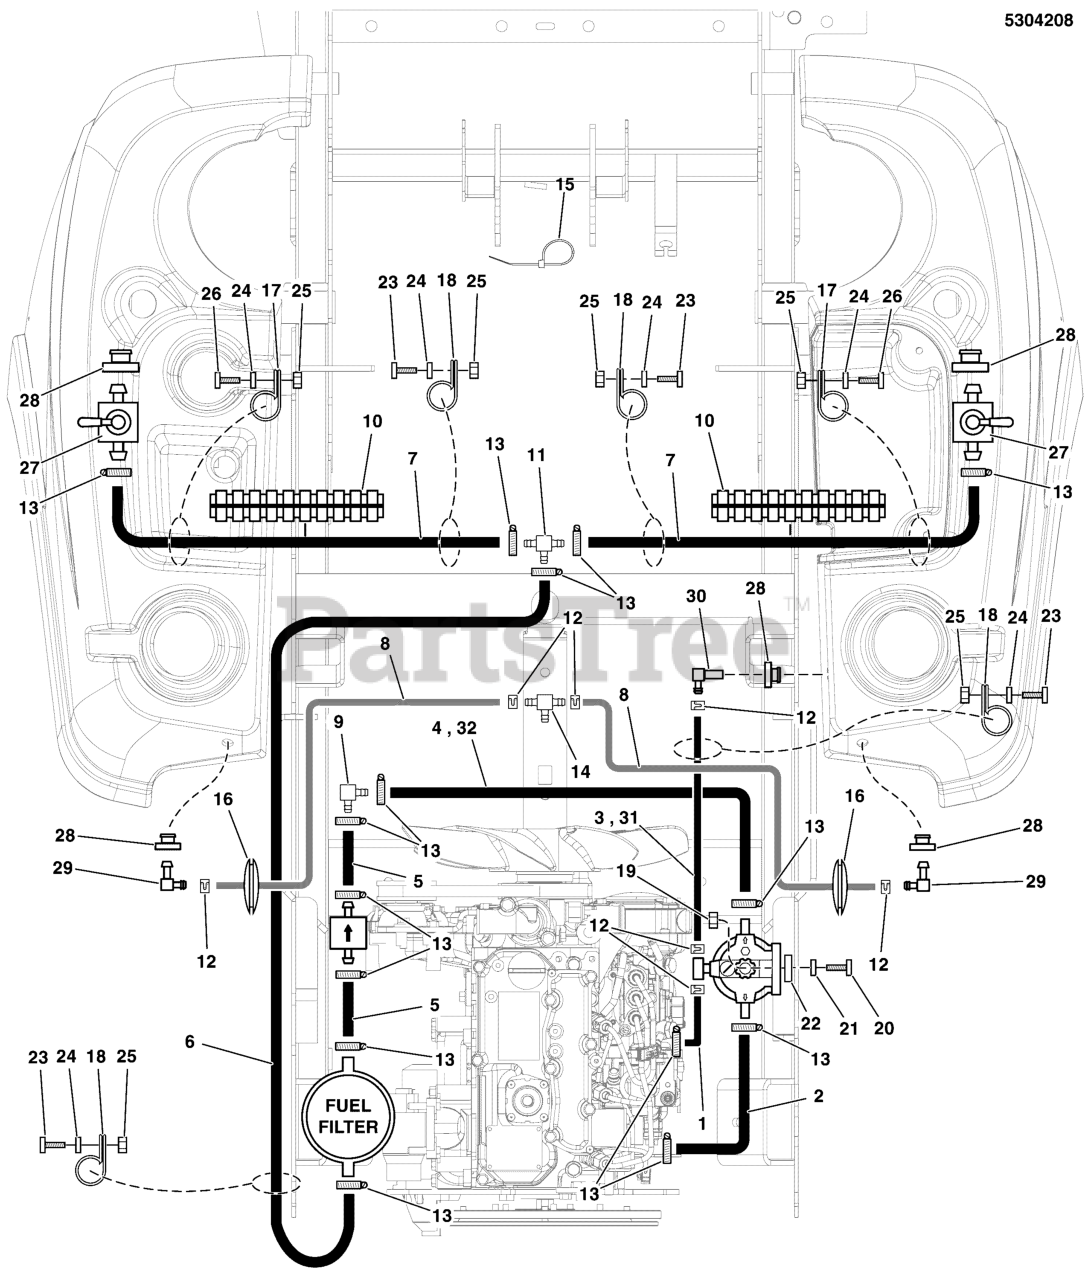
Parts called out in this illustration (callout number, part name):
1	HOSE, 1/4" FUEL, 22.50"
2	FUEL HOSE, 5/16 ID X 21.00
3	HOSE, 1/4" FUEL, 57.50"
4	FUEL LINE, 5/16 ID X 32.00 IN
5	FUEL LINE, 5/16 ID X 2.00 IN
6	FUEL HOSE, 5/16 ID X 40"
7	FUEL HOSE, 5/16 ID X 25.50
8	HOSE, 1/4" FUEL, 19.00"
9	FITTING, 5/16 X 5/16, 90 ELBOW DAPCO.
10	WIRE LOOM, 5/8 ID X 23.5"
11	FITTING, TEE, 5/16 HOSE
12	CLAMP, HOSE, EXTERNAL, 1/2 - RED
13	CLAMP, #4 HOSE, STAINLESS
14	1/4 BARBED TEE
15	TIE, SELF-LOCKING, 12"
16	GROMMET, 5/8 ID X 1/8 MATERIAL
17	CLAMP, VINYL INSULATED, 1.00
18	CLAMP, VINYL INSULATED, .625
19	NUT, 5/16-18 HEX NYLOCK FLANGE
20	BOLT, 5/16-18 X 3-3/4 GD5 CZ
21	WASHER, 5/16" SAE
22	SPACER, .33 X .63 X .50, CZ
23	BOLT, 1/4-20 X 3/4 GD5 CZ
24	WASHER, 1/4 SAE
25	NUT, 1/4-20 HEX NYLOCK FLANGE
26	HHCS, 1/4-20 X 0.625, GR5, ZINC/CLEAR
27	FITTING, 5/16 FUEL SHUT-OFF
28	BUSHING-FUEL TANK RED RUBBER
29	FITTING, DAPCO, 3/8" 90 ELBOW DAPCO
30	FITTING, 5/16 X .40, 90 ELBOW DAPCO
31	HOSE, 1/4" FUEL, 60"
32	FUEL LINE, 5/16 ID X 34.00 IN
